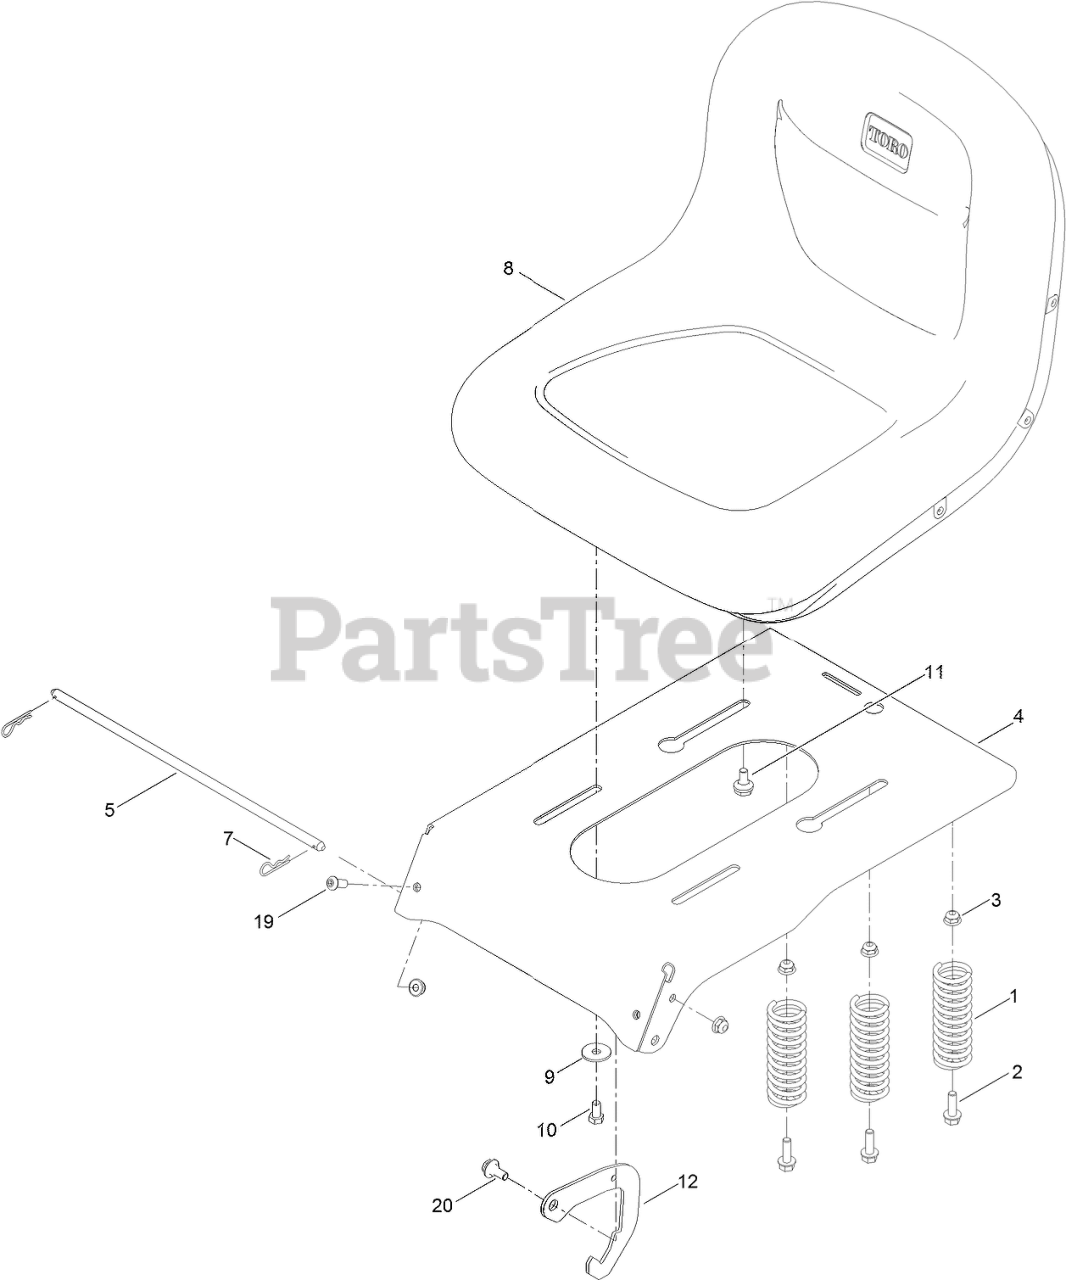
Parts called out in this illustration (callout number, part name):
1	SPRING-COMPRESSION
2	SCREW-HHF
3	NUT-HF
4	PAN-SEAT
5	ROD-PIVOT, NARROW
7	PIN-COTTER
8	SEAT-15 INCH
9	WASHER-PIVOT
10	SCREW-HH
11	BOLT-SHOULDER,HFH
12	SEAT LATCH
19	SCREW-HSBH
20	SCREW-SHOULDER
